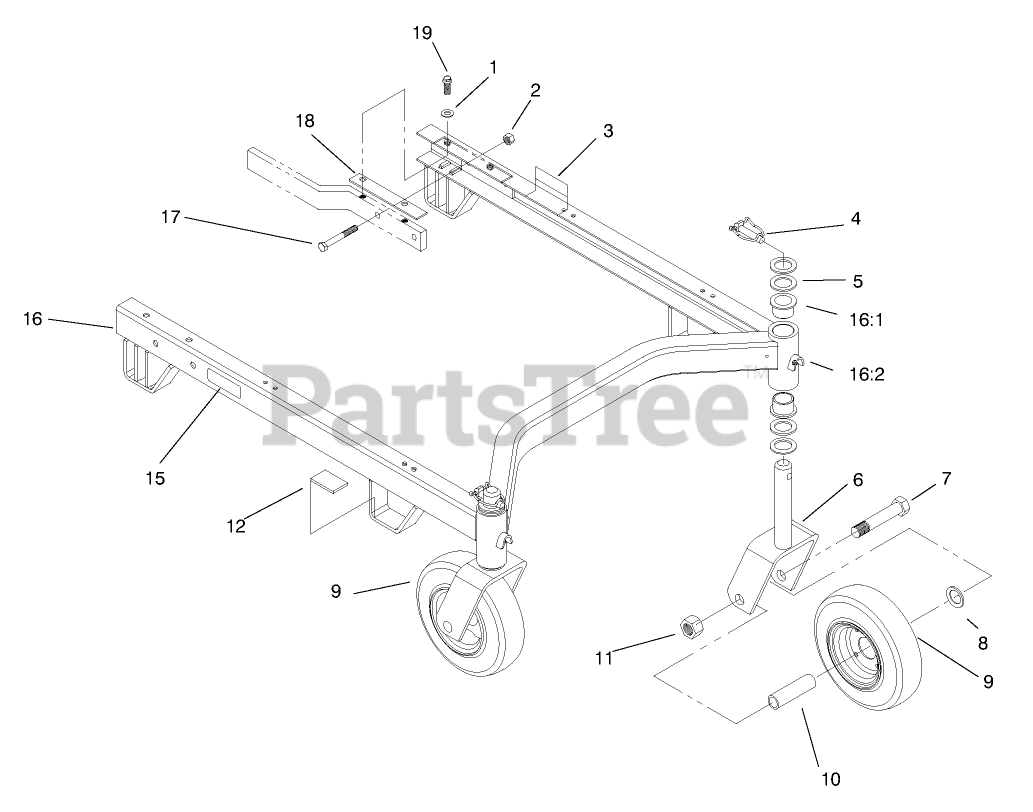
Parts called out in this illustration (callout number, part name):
1	WASHER-FLAT
2	NUT-LOCK, CONE
3	DECAL-HOC, LH
4	PIN-LYNCH
5	WASHER-THRUST
6	Castor Fork
7	SCREW-HH
8	WASHER-FLAT
9	TIRE AND BEARING ASM
10	SPANNER-TIRE
11	NUT-HEX
12	CUSHION-RUBBER
15	DECAL-HOC, RH
16	SUSPENSION W A
16:1	BUSHING
16:2	FITTING-GREASE
17	SCREW-HH
18	SHIM-CARRIER
19	SCREW-HHF
